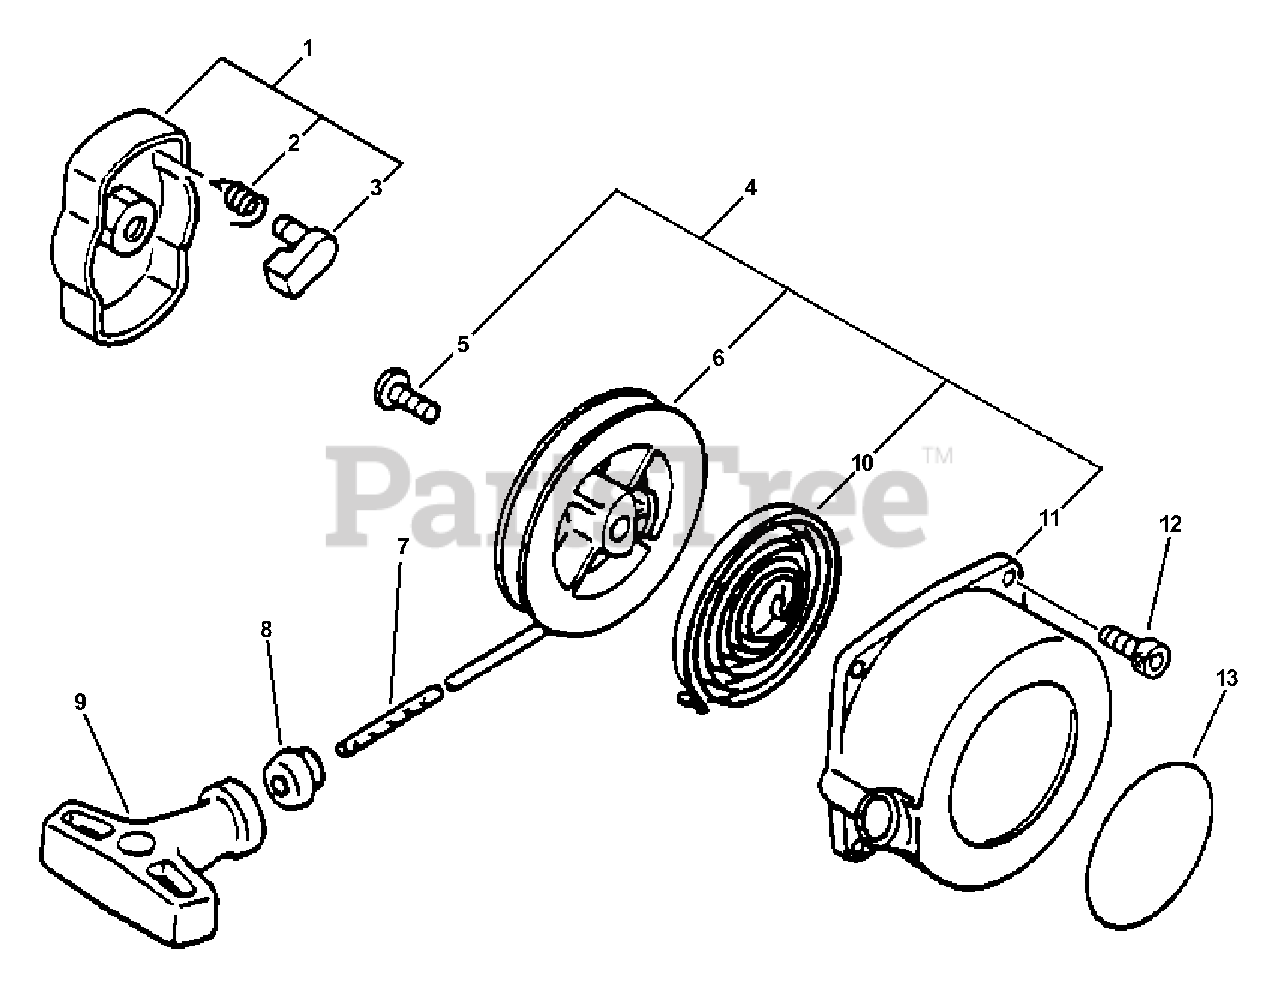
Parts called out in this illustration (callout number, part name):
1	PAWL ASSY, STARTER
2	SPRING, RETURN
3	PAWL, STARTER - BLACK
4	STARTER ASSY, RECOIL
5	SCREW
6	REEL, ROPE
7	ROPE, STARTER 3.0×1000
8	GUIDE, ROPE
9	GRIP, STARTER
10	SPRING, RECOIL
11	CASE, RECOIL STARTER
12	BOLT 4×16
13	LABEL, ECHO
